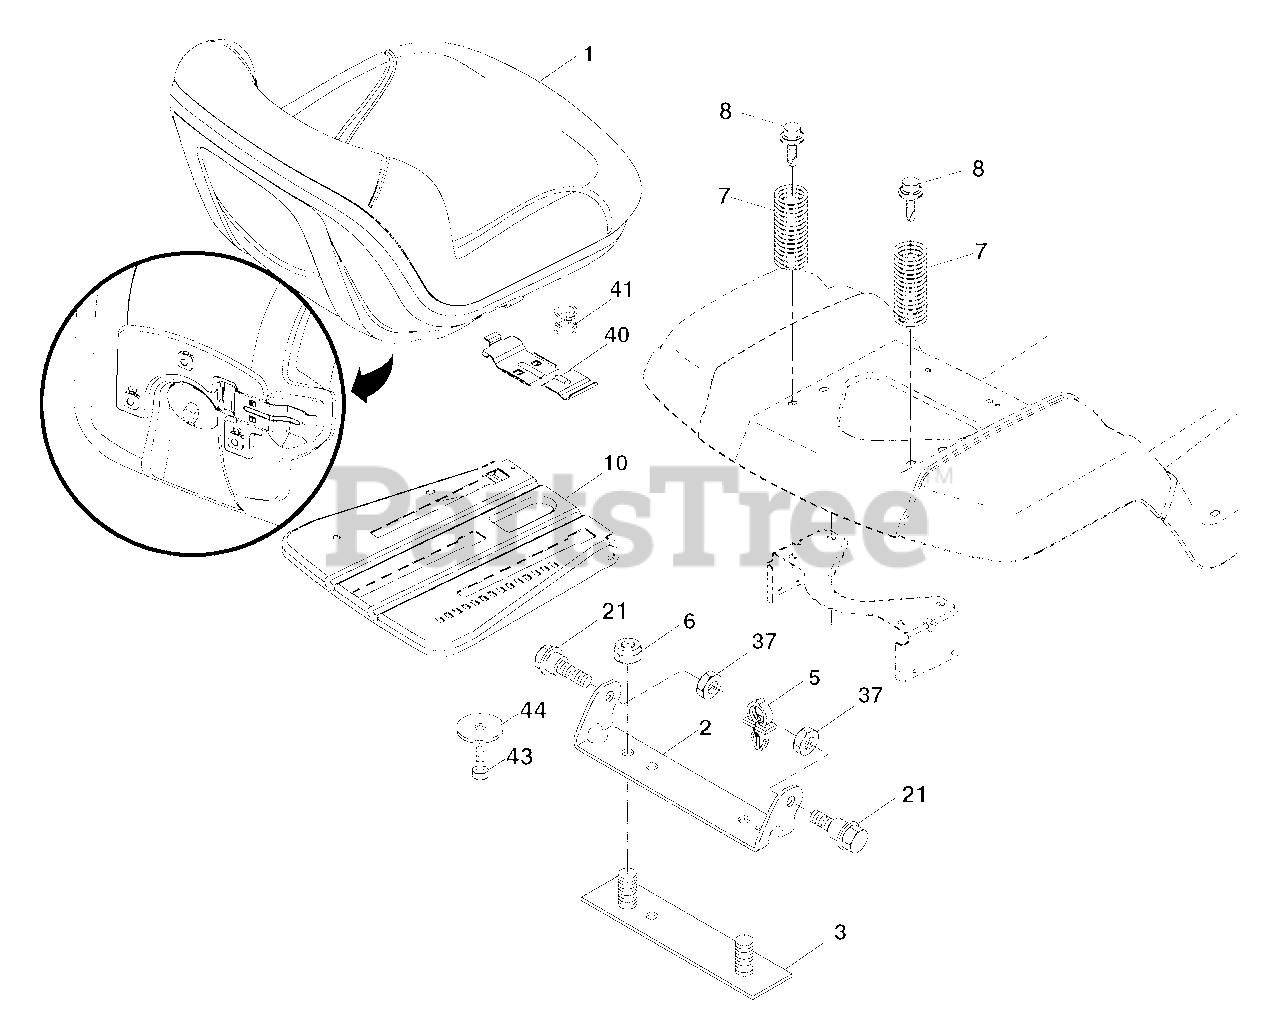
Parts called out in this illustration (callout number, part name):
1	Seat
2	Bracket Pivot Fender
3	Strap, Asm Fender
5	Clip, Push In, Hinged
6	Nut, Lock W/Ins. 3/8-16 unc
7	Spring, Seat Cprsn
8	Bolt 5/16-18 uncx 3/4 w/Sems
10	Pan, Seat
21	Bolt, Shoulder 5/16-18
37	Nut, Lock 5/16-18 unc
40	Handle Slide Seat
41	Spring Latch Seat
43	Bolt Fin Hex 3/8-16 unc x 3/4
44	Washer 13/32 x 2-3/8 x 12 Ga.
